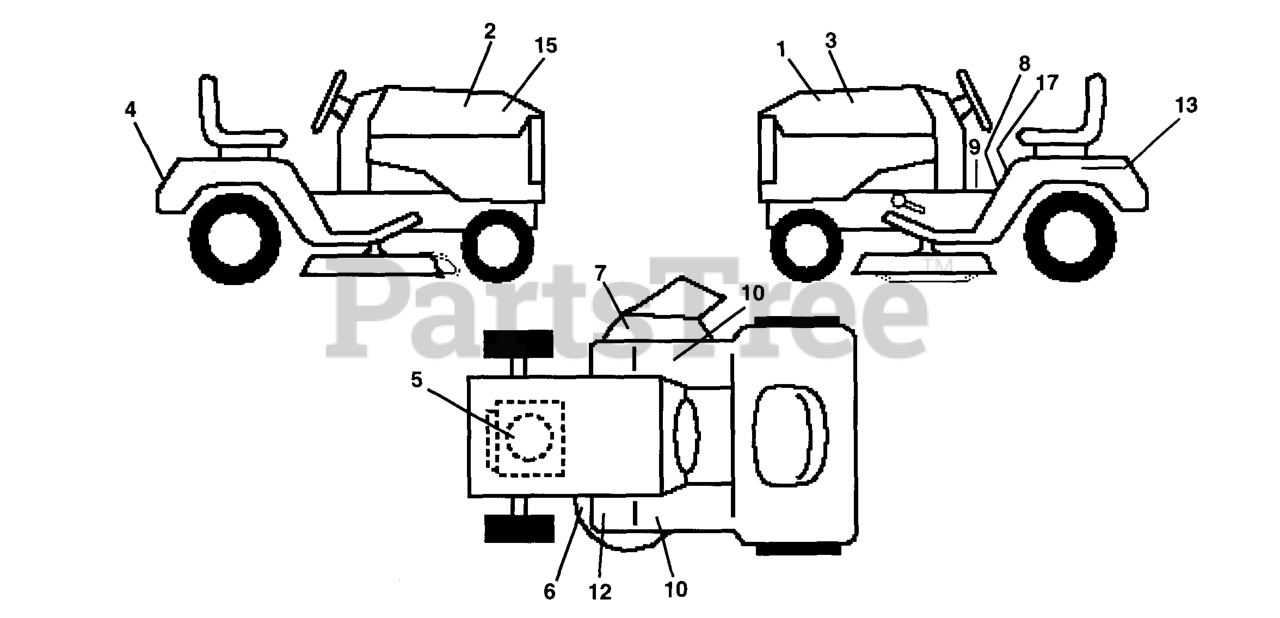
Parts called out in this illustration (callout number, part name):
1	DECAL HOOD LH
2	DECAL HOOD RH
3	DECAL PANEL LH
4	DECAL FENDER NLA
5	DECAL ENGINE
6	DECAL V-BELT SCHEMATIC
7	DECAL WARNING (ENGLISH/FRENCH)
8	DECAL DASH
10	FOOTREST PAD
15	DECAL PANEL RH
17	DECAL CAUTION
